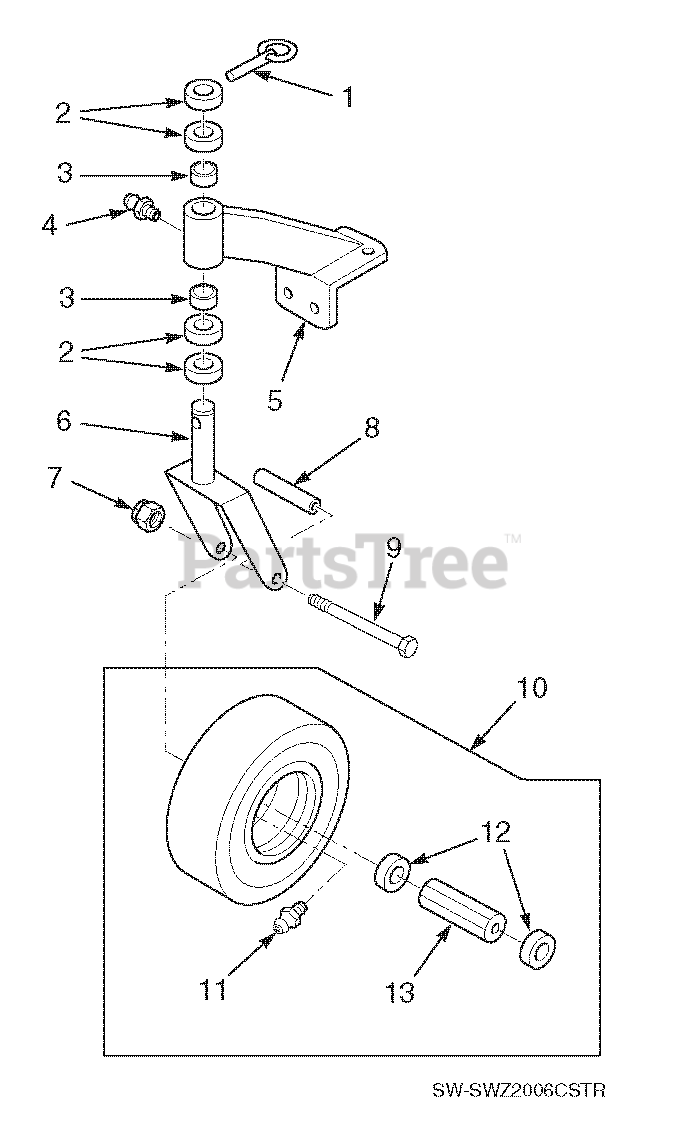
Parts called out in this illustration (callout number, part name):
1	Quick Pin
2	Spacer, Spacer Yoke, 1/2" Long
3	Bronze Bearing
4	Greasing Fitting
5	Support Assembly
6	Caster Yoke
7	Nut, Elastic Stop 1/2-13
8	Sleeve, Caster Wheel Bearing
9	Bolt, Hex Head 1/2-13 x 5-1/2"
10	Flat-Free Tire Assy.
11	Grease Fitting, 45 Degree 1/4-28
12	Retainer, Caster Wheel Bearing
13	Roller Bearing, Caster Wheel
